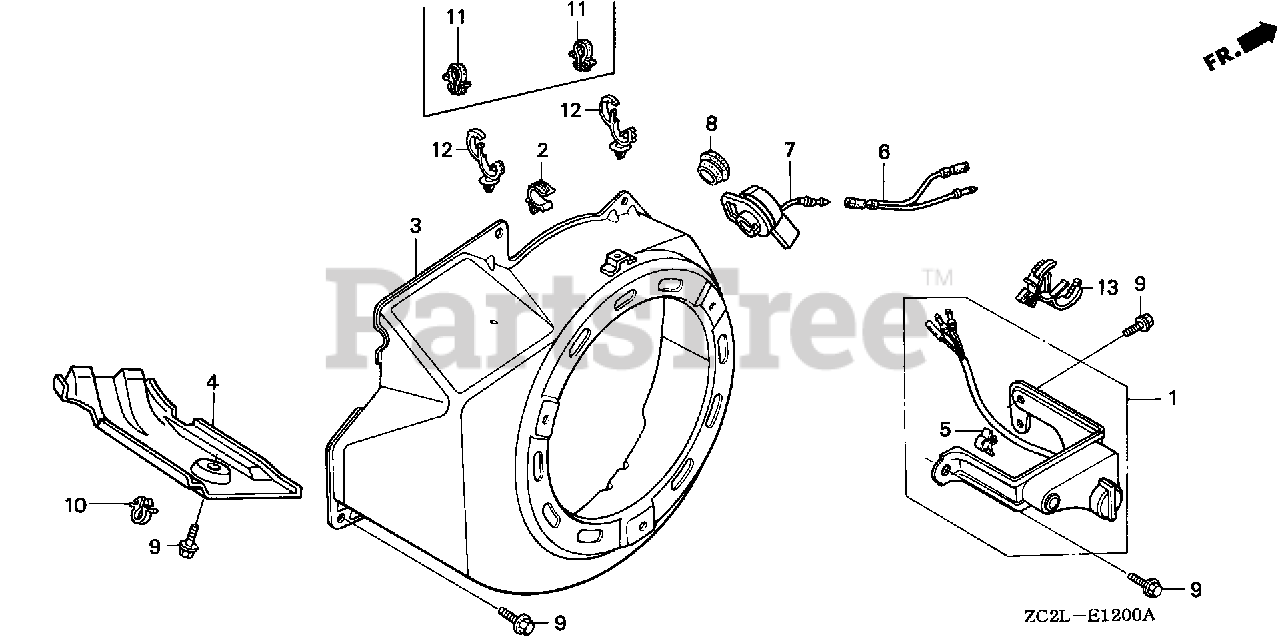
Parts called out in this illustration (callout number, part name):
2	CLIP, TUBE
3	COVER, FAN *NH1* (BLACK)
7	SWITCH ASSY., ENGINE STOP
9	BOLT, FLANGE (6X12) (CT200)
13	CLIP, HARNESS
